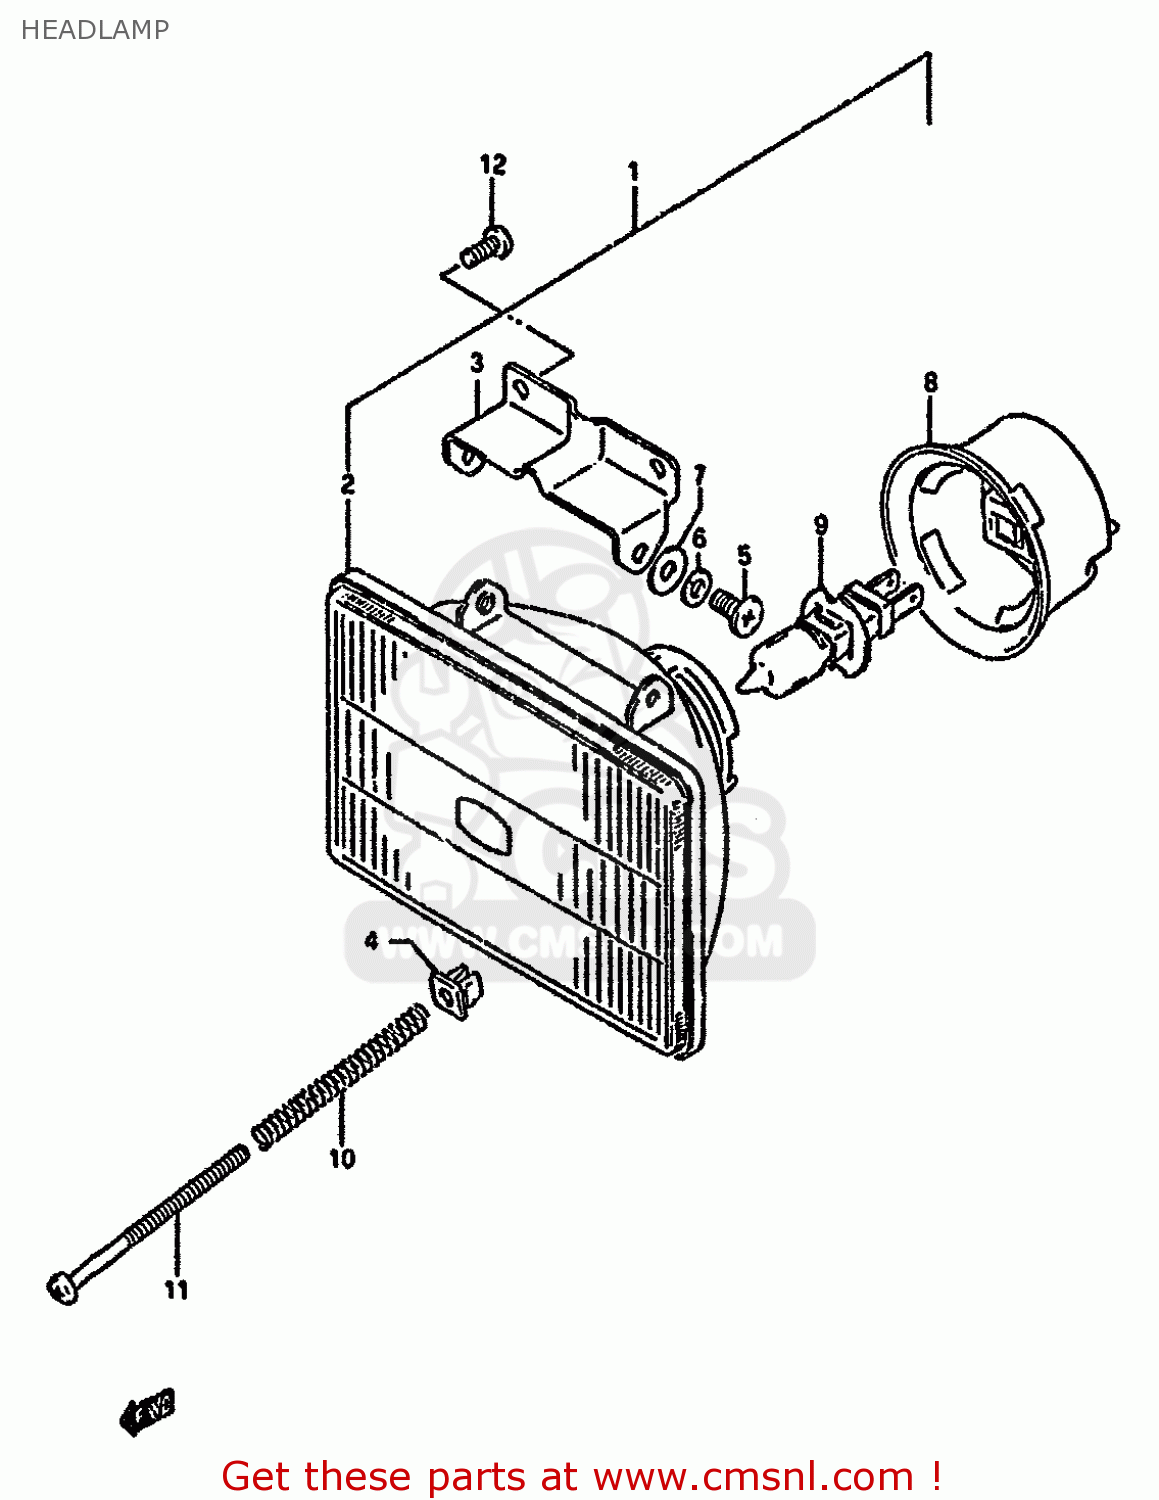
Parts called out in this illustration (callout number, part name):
1	HEADLAMP ASSY
2	UNIT,LAMP
3	BRACKET,LAMP
4	NUT,HEADLAMP ADJUSTER
5	SCREW
6	LOCK WASHER
7	WASHER
8	COVER,SOCKET
9	BULB(12V55W)
10	SPRING,HEAD LAMP ADJUSTER
11	SCREW,HEADLAMP ADJUST
12	SCREW
